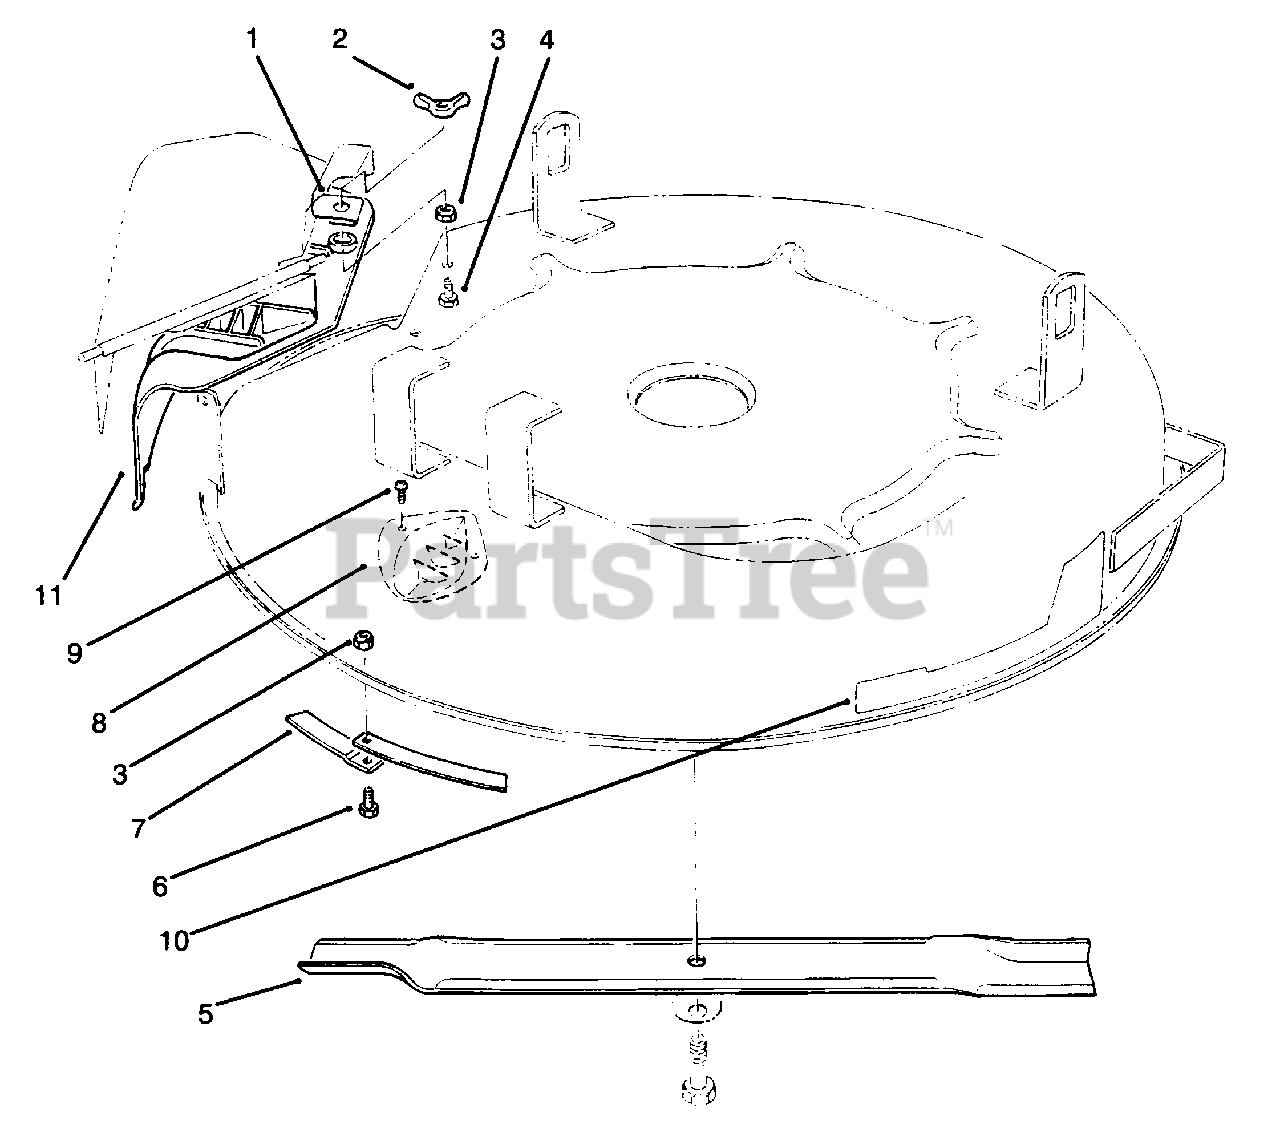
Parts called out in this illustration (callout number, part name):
3	Nut-Lock
4	Screw (Provided w/Cutting Unit)
5	Blade-Recycler
6	Screw-Cap Hex. Hd.
7	Ring-Deck
9	Screw-Special
10	Decal-Recycler
11	Cover-Recycler
